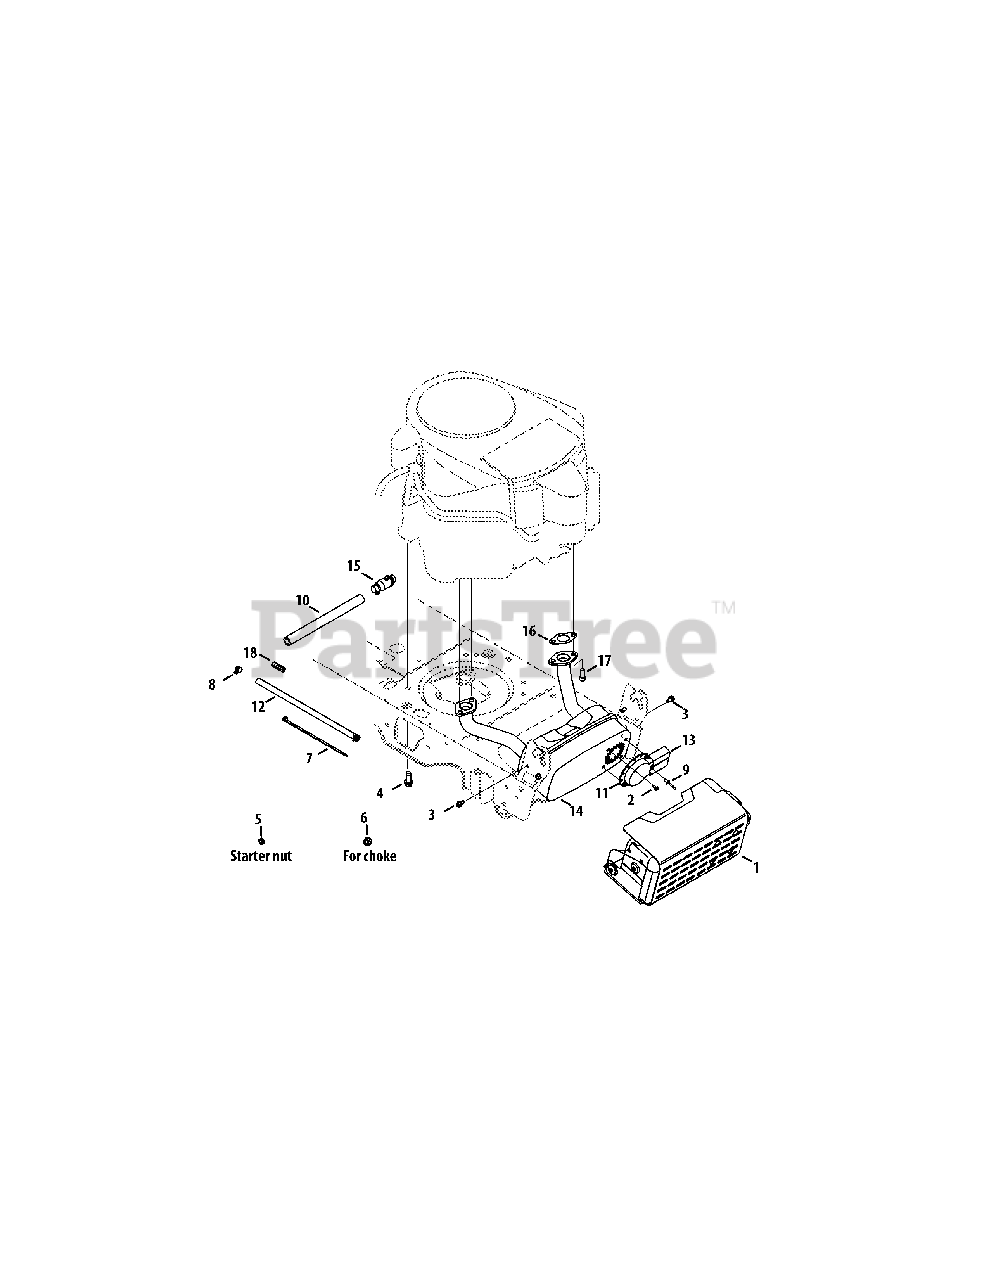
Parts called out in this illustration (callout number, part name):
1	Shield Ass’y, Muffler
2	Screw, Ab, #8-18, 0.500,
3	Screw, Self-tapping, 1/4-20, 0.500,
4	Screw, Self-tapping, 3/8-16, 1.0
4	Screw, Self-tapping, 3/8-16, 1.25
5	Nut, Sems, 1/4-20
6	Nut, Flange Lock, 3/8-16
7	Cable, Tie, 3/16 x .05 x 7.4
8	Clamp, Hose, .490 Dia.
9	Rivet, Pop, .188 Dia x .300
10	Hose, Extension, Oil Drain
11	Deflector, Muffler
12	Hose, Fuel, Low Permeation, 1/4
13	Deflector, Muffler, Long
14	Muffler, Kohler
14	Muffler, Kawasaki Twin
15	Drain, Oil
16	Gasket, Exhaust,
17	Screw, Socket Head, 5/16-18, .750
18	Hose, Vent
